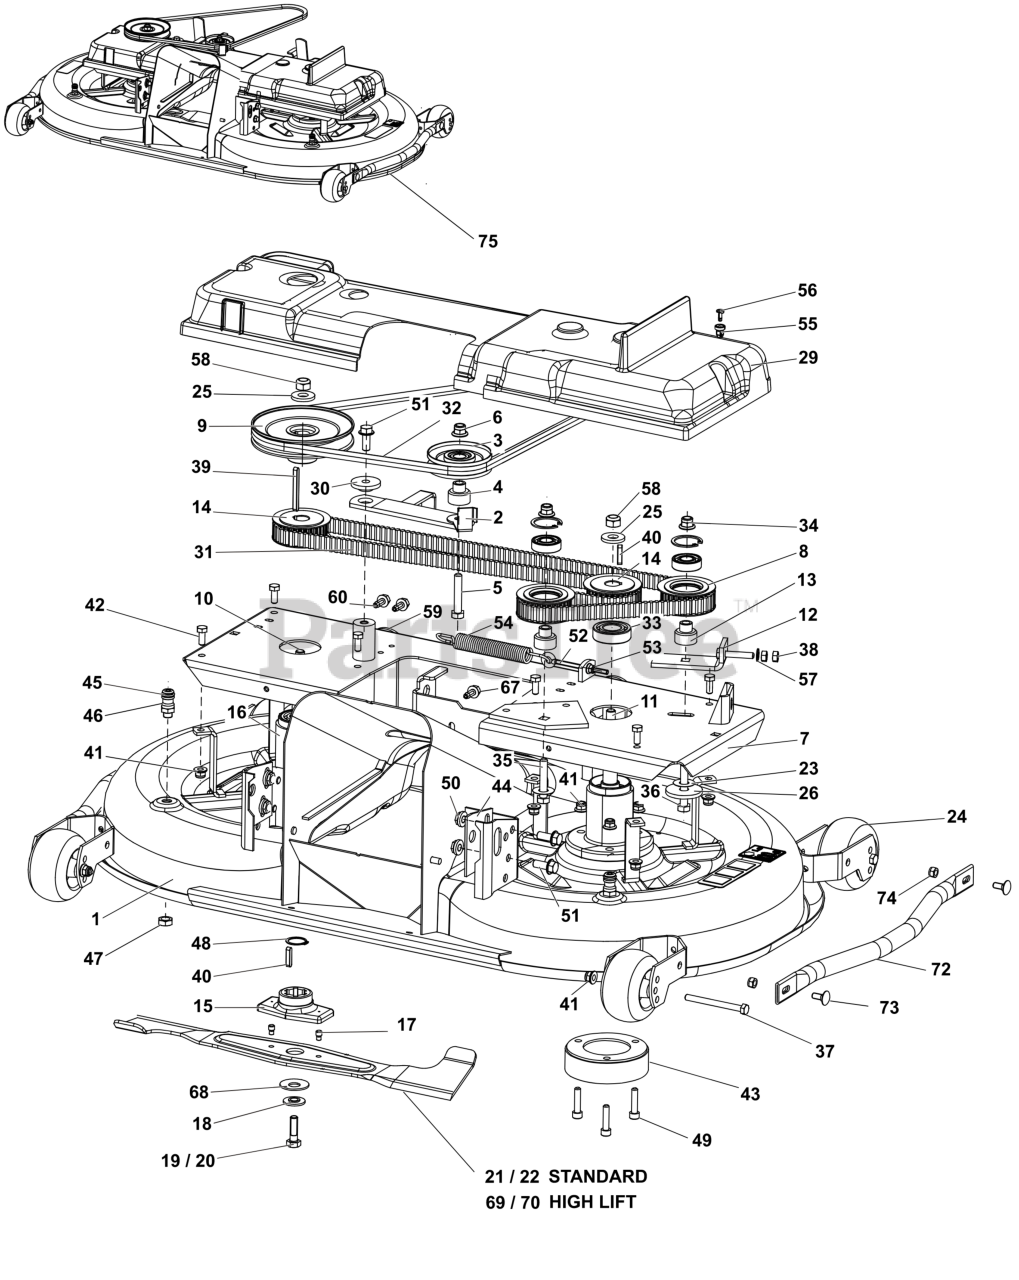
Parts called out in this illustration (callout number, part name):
1	MOWER DECK
7	CASE, Main
12	FOOT, Mounting
17	STUD ( 100 PCS )
21	BLADE, Left, 122cm
22	BLADE, Right, 122cm
29	COVER, Belt
45	CONNECTOR
69	BLADE, High Lift, Left, 122cm
70	BLADE, High Lift, Right, 122cm
72	BUMPER, Tube
75	KIT, Mower Deck
